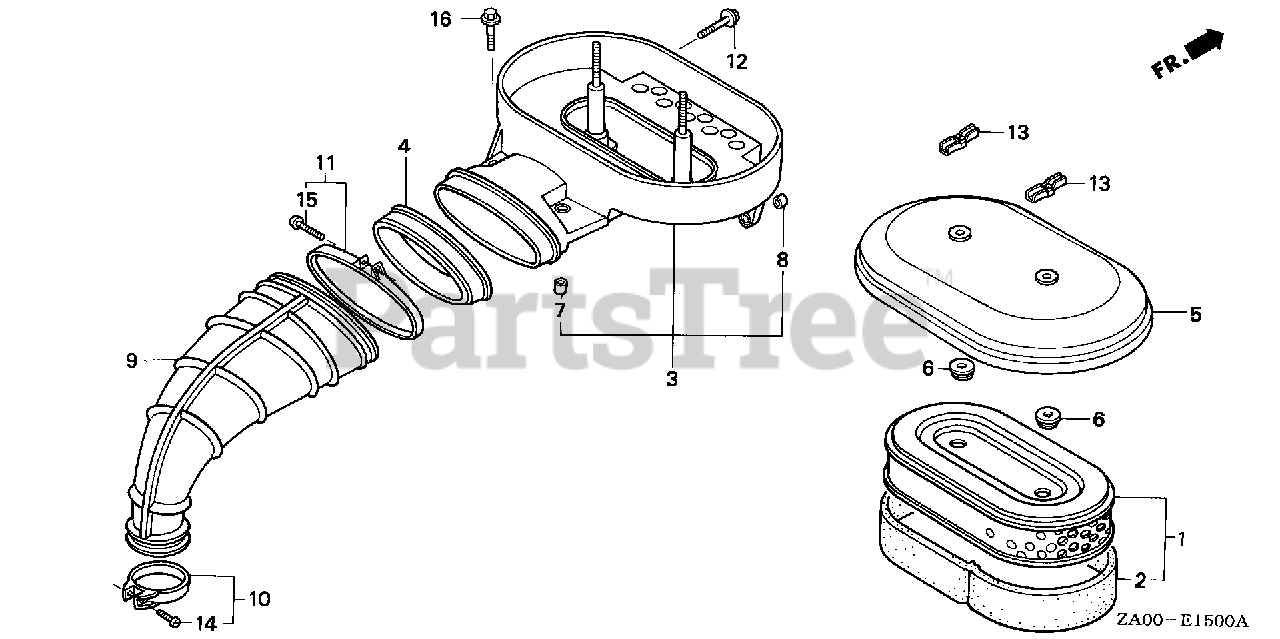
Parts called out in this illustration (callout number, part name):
1	ELEMENT, AIR CLEANER (DUAL)
1	ELEMENT, AIR CLEANER
2	FILTER (OUTER)
3	HOUSING, AIR CLEANER
4	SUPPORTER, AIR CLEANER (NOT AVAILABLE)
5	COVER, AIR CLEANER
6	GROMMET, AIR CLEANER
7	COLLAR A, AIR CLEANER
8	COLLAR B, AIR CLEANER
9	TUBE, AIR CLEANER CONNECTING
10	BAND, CONNECTING TUBE
11	BAND ASSY., CONNECTING TUBE
12	BOLT, FLANGE (6X25) (CT200)
13	NUT, AIR CLEANER COVER (DACRO COATING)
14	SCREW, PAN (4X16)
15	SCREW, PAN (4X25)
16	BOLT, FLANGE (6X35)
